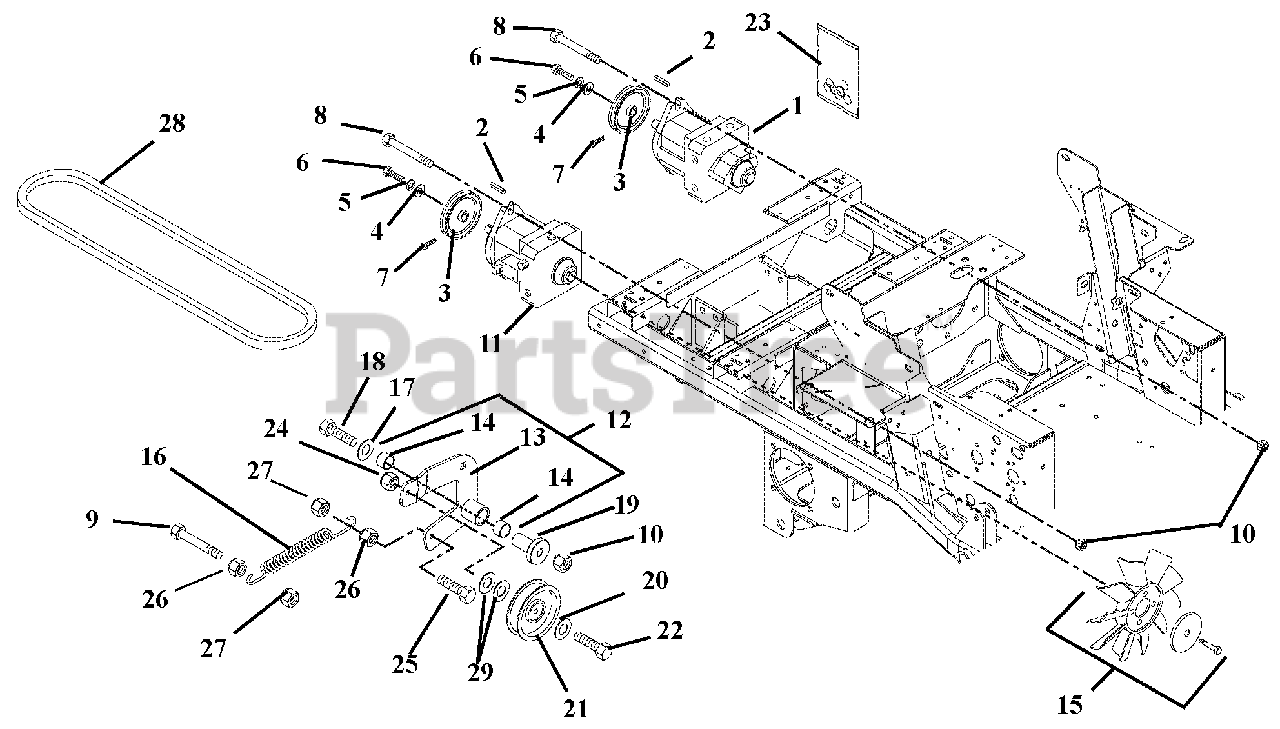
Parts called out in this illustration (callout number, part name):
1	Pump, Hydraulic (RTN) with Auxiliary
2	Key, Square 5 x 5 x 30mm Plain
3	Sheave, Poly-V .671 x 4.125
4	Washer, Pump .28 x 1.25 x .50
5	Washer, Locking .25 x .062
6	Bolt, Hex M6 x 1 x 16
7	Screw, Socket Head .25-20 x .50
8	Bolt, Hex .50-13 x 1.50 Grade 5
9	Bolt, Hex .31-18 x 2.50 Grade 5
10	Nut, Locking Top Flange .50-13
11	Pump, Hydraulic (RTN)
12	Assembly, Idler Arm Guard Drive (Includes 13 & 14)
13	Weldment, Idler Arm Ground Drive
14	Bearing, 1.00 x 1.12 x .75
15	Fan, Hydro Pump Cooling
16	Spring, Tension .120 x .845 x 6.500
17	Washer, Flat Steel .39 x.75 x.125
18	Bolt, Hex .50-13 x 3.50 Grade 5
19	Bearing, Pedestal Powdered Metal
20	Washer, Flat Steel .406 x .812 x .065
21	Idler, Flat .377 x 4.0 x .96 Poly
22	Bolt, Hex .38-16 x 2.0 Grade 5
23	Kit, Pump Seal (One kit required for each pump)
24	Nut, Locking Top Flange .38-16
25	Bolt, Hex .31-18 x 1.25 Grade 5
26	Nut, Hex .31-18
27	Nut, Locking Top Flange .31-18
28	Belt, Poly-V 49.50, Hydrostatic 200Z Series
29	Washer, Flat Steel .390 x .75 x .125
